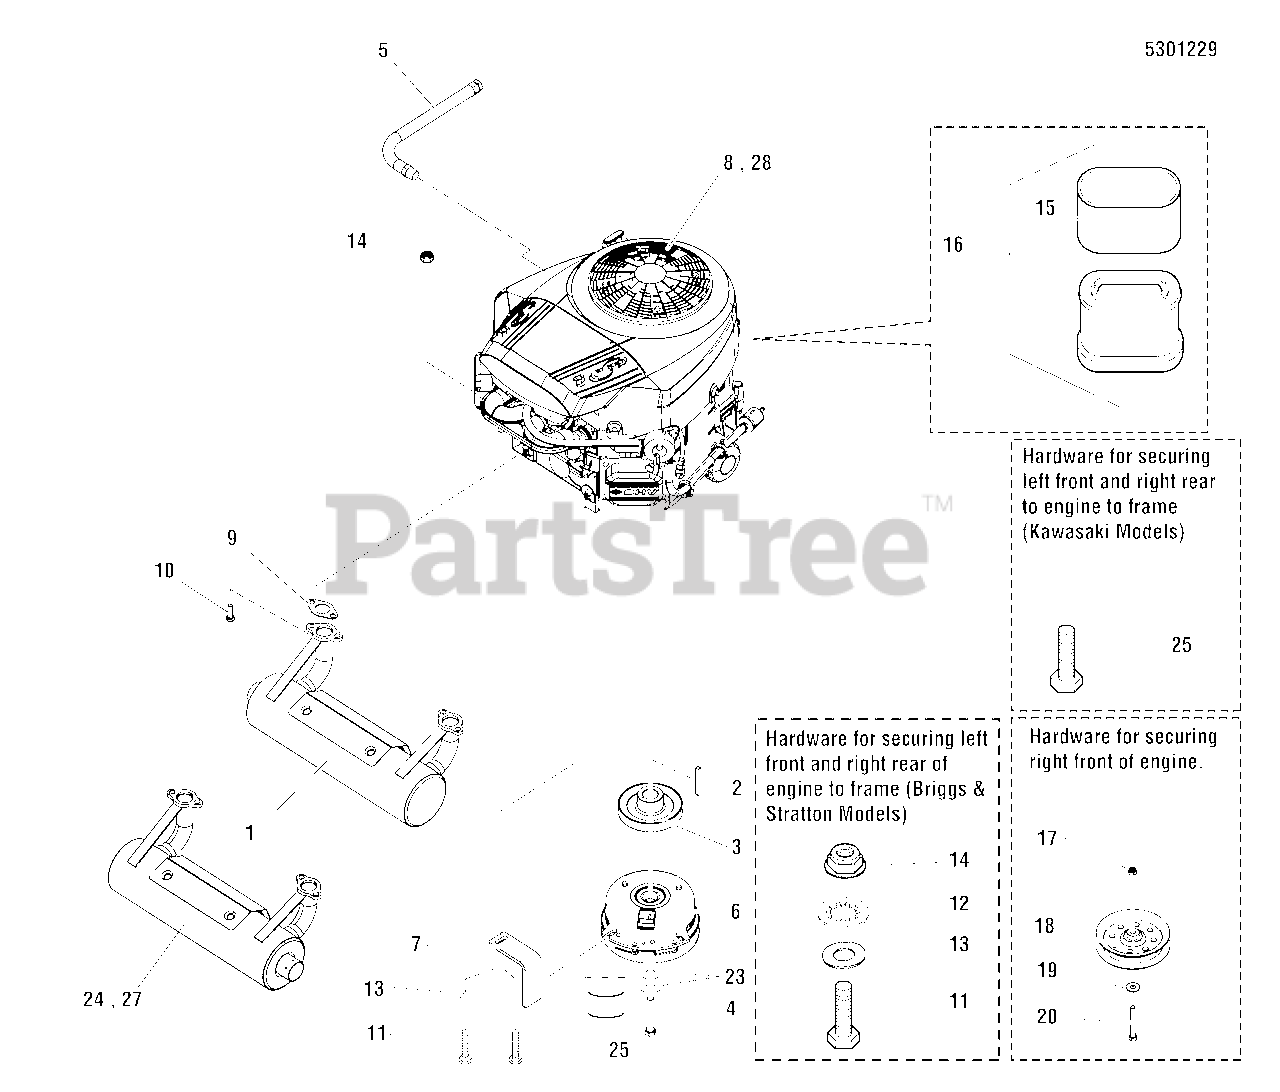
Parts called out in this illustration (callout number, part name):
1	MUFFLER, B&S-ELS
2	KEY, 1/4 SQ. X 1.00
3	PULLEY, PUMP DRIVE, 4.857 OB X 1" BORE
4	BOLT, CRANKSHAFT, 7/16 X 2-3/4
4	BOLT, CRANKSHAFT, 7/16-20 X 3, GD8
5	HOSE, OIL DRAIN
6	CLUTCH, # 5219-34A, ELECTRIC, IS500Z
7	ANCHOR, CLUTCH - BLK
8	* ENGINE, B&S 25HP, Model 44T877-9322-21
8	* ENGINE, B&S, 26HP ELS, Model 44P777-6169-G5
8	* ENGINE, B&S, 27HP ELS, Model 44Q777-5146-G5
9	GASKET, Exhaust
10	SCREW
11	BOLT, 5/16-18 X 1-3/4 GD5 YZ
12	WASHER, 5/16" INT. TOOTH LOCK
13	WASHER, 5/16" SAE
14	NUT, 5/16-18 HEX NYLON LOCK
15	* PRE CLEANER (SV)
16	* AIR CLEANER W/ PRE CLEANER (SV)
17	SEE PUMP DRIVE GROUP
18	SEE PUMP DRIVE GROUP
19	SEE PUMP DRIVE GROUP
20	SEE PUMP DRIVE GROUP
23	BELLEVILLE WASHER 1.1875 X .442 X .089
24	MUFFLER, RIGHT OUTLET ASSY
25	BOLT, 3/8-16 X 1-1/4, SF, PLT W/PATCH
27	MUFFLER
28	* ENGINE, KAWASAKI 21.5 HP FR651V-FS00-S
